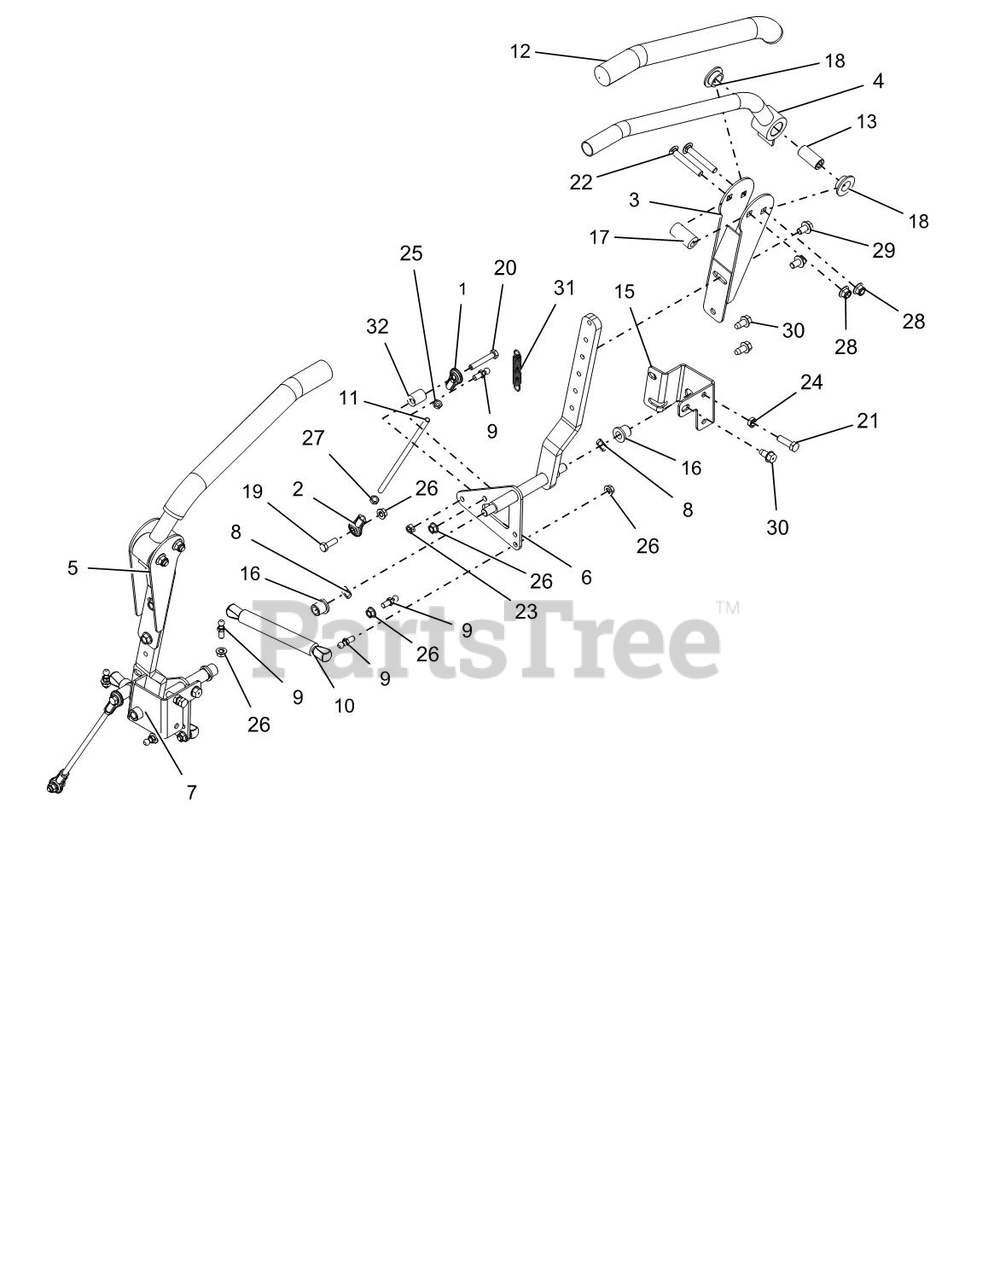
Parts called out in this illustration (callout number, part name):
1	ALIGNABALL, 5/16 RH THREAD
2	ALIGNABALL, 5/16 LH THREAD
3	UPPER ADJ CNTRL ARM WLDMT- BLK
4	WLDMT, LH DRIVE CONTROL HANDLE
5	WLDMT, RH DRIVE CONTROL HANDLE
6	WLDMT, LH LOWER CONTROL ARM
7	WLDMT, RH LOWER CONTROL ARM
8	WAVE WASHER .531X.781X.125FH
9	STUD- BALL
10	DAMPER
11	ROD, STEERING
12	GRIP, HANDLEBAR
13	SPACER, STEERING ARM
15	PT200/400 LH CNTRL STP BRK-RED
16	BHSG-FLG .500X.750X.750X.125
17	BSHG, ECCENTRIC.406X.875X1.625
18	BSHG-FLG .762X1.48X.44 NYL
19	BLT-HEX .31-18X1.00 GR5 YWZC
20	BLT-HEX .31-18X2.00 GR5 YWZC
21	BLT-HEX .38-16X1.25 GR5 YWZC
22	BLT-RDHDSQSHK, 38-16X2.50 G5YZ
23	NUT-LK-CTR .31-18 YWZC
24	NUT-HEX-JAM .375-16 YWZC
25	NUT-JAM .31-24 YWZC
26	NUT-LK-TOP-FLG .31-18 YWZC
27	NUT-JAM LH .31-24 YWZC
28	NUT-LK-NYL-FLG .38-16 YWZC
29	BLT, SCRHFWH .375-16X.625 YWZC
30	SCR-TAP .38-16X.75 HWH TR YWZ
31	SPRING,EXT,.061X.50X3.0
32	ECCENTRIC
